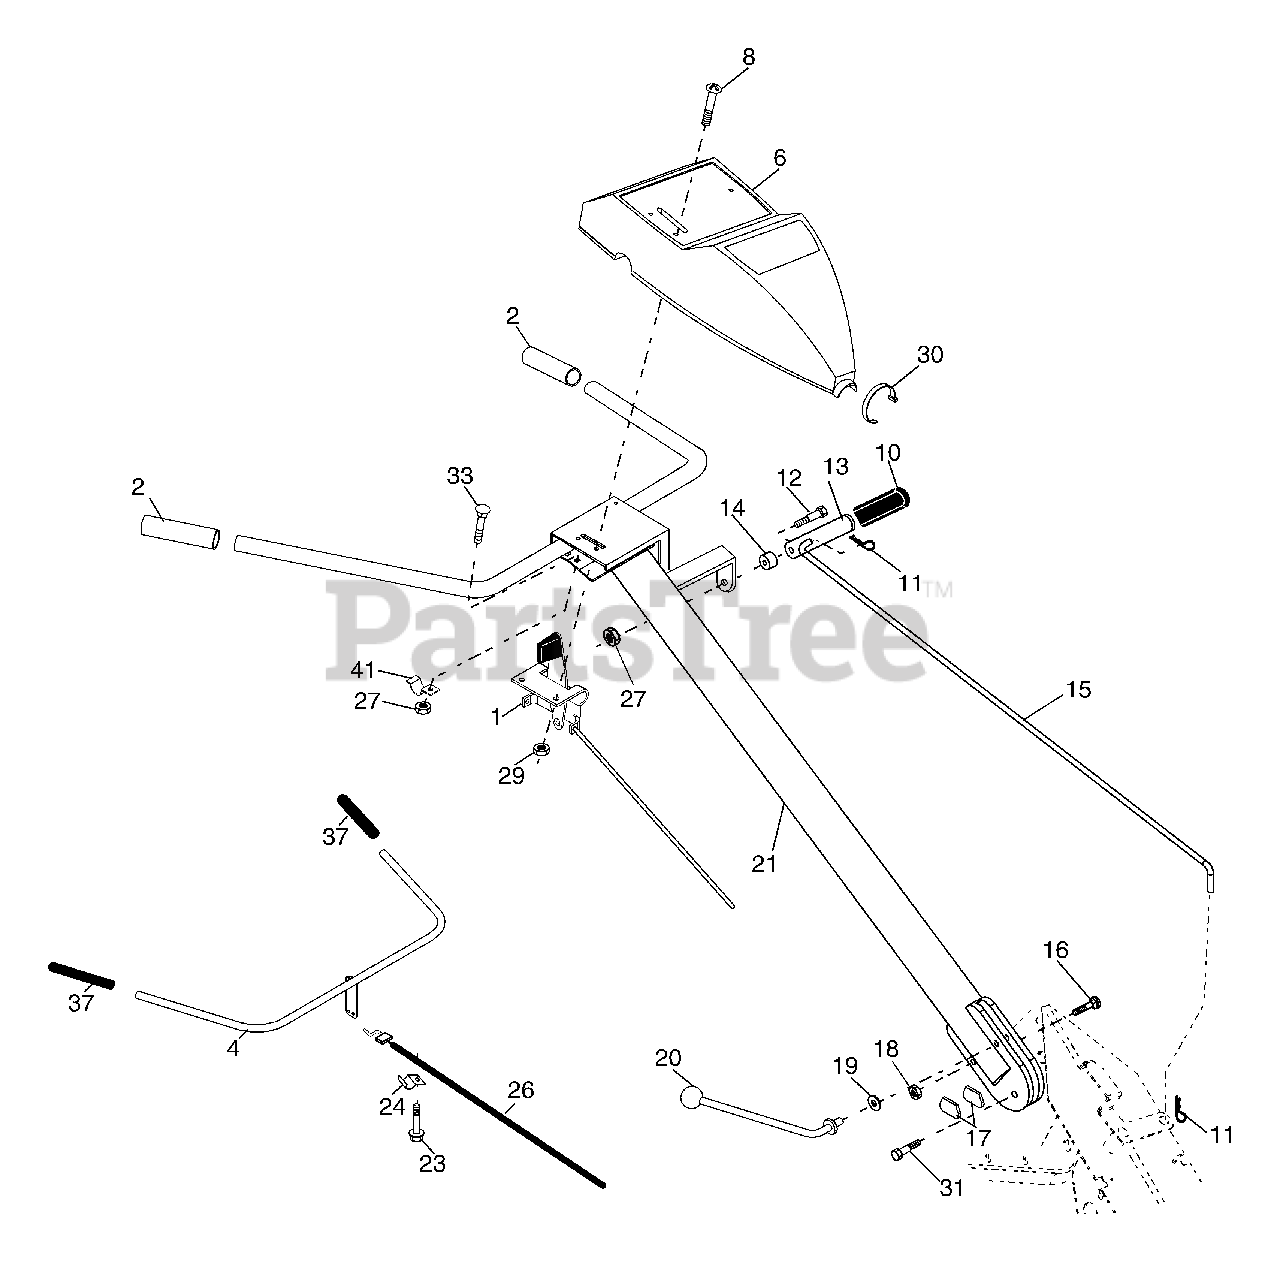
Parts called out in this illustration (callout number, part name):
1	Control, Throttle
2	Grip, Handle
4	Bar Assembly, Control
6	Panel, Control
8	Screw, Truss Hd. #10-24 unc x 1/2
10	Grip, Handle
11	Clip, Hairpin
12	Bolt, Shoulder
13	Handle, Shift
14	Grommet, Rubber
15	Rod, Shift
16	Bolt, Carriage 3/8-16 x 1 Gr. 5
17	Lock, Handle
18	Nut, Crownlock 3/8-16 unc
19	Washer 13/32 x 1 x 11 Ga.
20	Lever, Lock, Handle
21	Handle
23	Screw, Hex Washer SLT #10-24 x .50
26	Cable, Clutch
27	Nut, Hex Flange 1/4-20 unc
29	Nut, Keps #10-24 unc
30	Tie, Cable
31	Bolt, Pivot
33	Bolt, Carriage 1/4-20 unc x 1/2
37	Grip, Bar, Control
41	Clamp, Bar, Control
